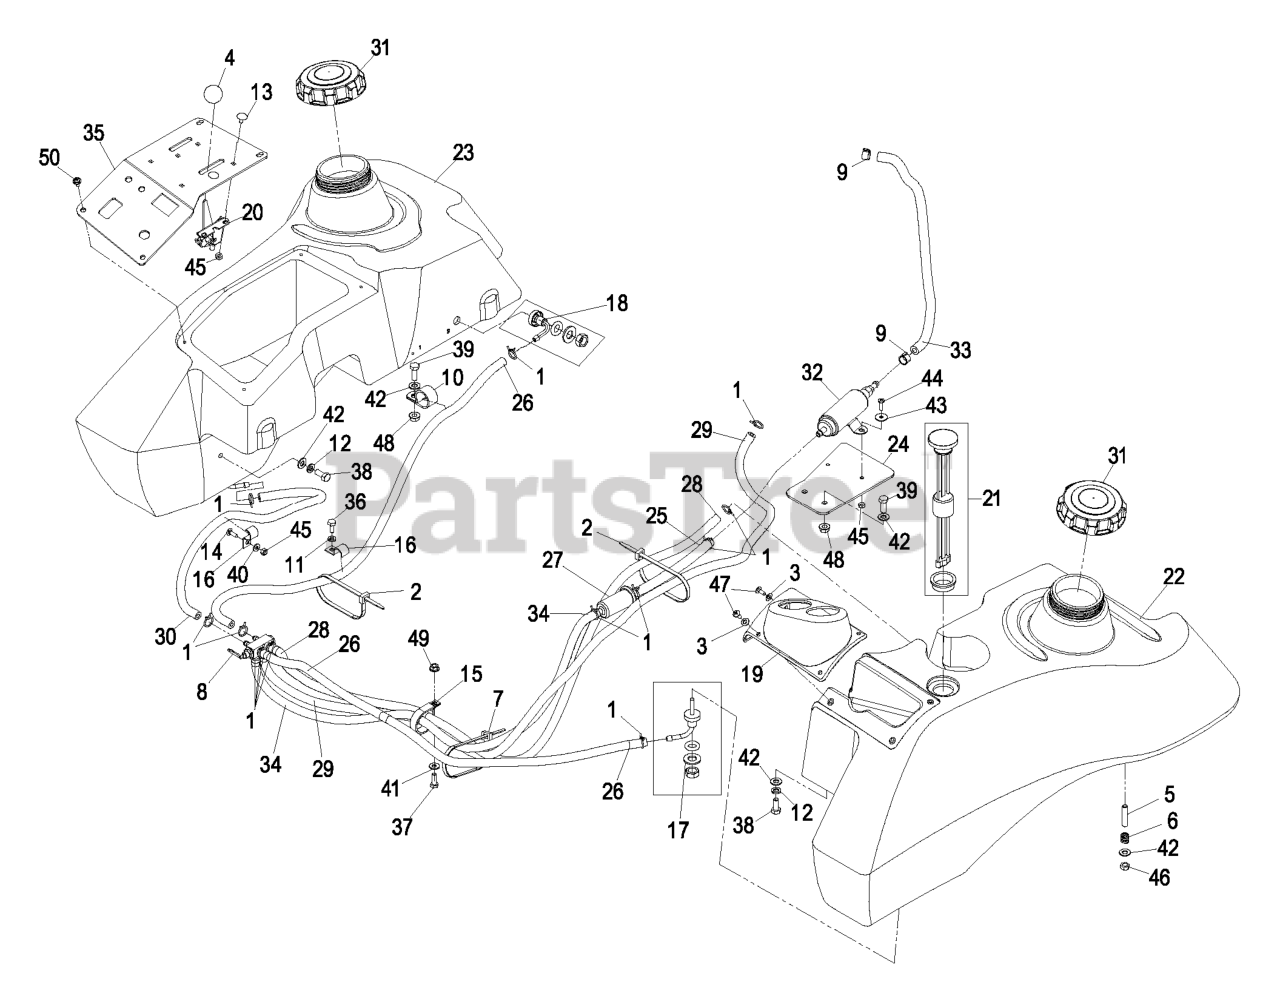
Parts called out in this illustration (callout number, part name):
2	TIE-PLASTIC
3	WASHER-SPRING
4	KNOB-BALL
5	STUD
6	SPRING-TANK, FUEL
7	TIE-PLASTIC
8	VALVE-FUEL, DUAL FLOW
9	CLAMP-HOSE, FUEL
10	CLIP-LOOM
11	WASHER-LOCK
12	WASHER-LOCK
13	BOLT-CARR
14	BOLT-CARR
15	CLIP-LOOM
16	CLIP-HALF, LOOM
17	FITTING-FUEL, BULKHEAD
18	FITTING-FUEL, BULKHEAD
19	BEZEL, GAGE XP LH TANK
20	CABLE-THROTTLE
21	KIT, CT FUEL GAGE REPL.
24	BRACKET, FUEL PUMP
25	HOSE-FUEL
26	HOSE-FUEL
27	Kawasaki P/N 49019-1055 Fuel, Filter
28	HOSE-FUEL
29	HOSE-FUEL
30	HOSE-FUEL
31	CAP-FUEL, GAS
32	PUMP-FUEL
33	KIT,FUEL LINE W/ CLAMPS
34	HOSE-FUEL
35	ASM,CONTROL PANEL
36	SCREW-HH
37	SCREW-HH
38	SCREW-HH
39	SCREW-HH
40	WASHER-FLAT
41	WASHER-FLAT
42	WASHER-PLAIN
43	WASHER-FLAT
44	SCREW-PPH
45	NUT-LOCK, NI
46	NUT-LOCK, NI
47	SCREW-PTH
50	SCREW-PPH
